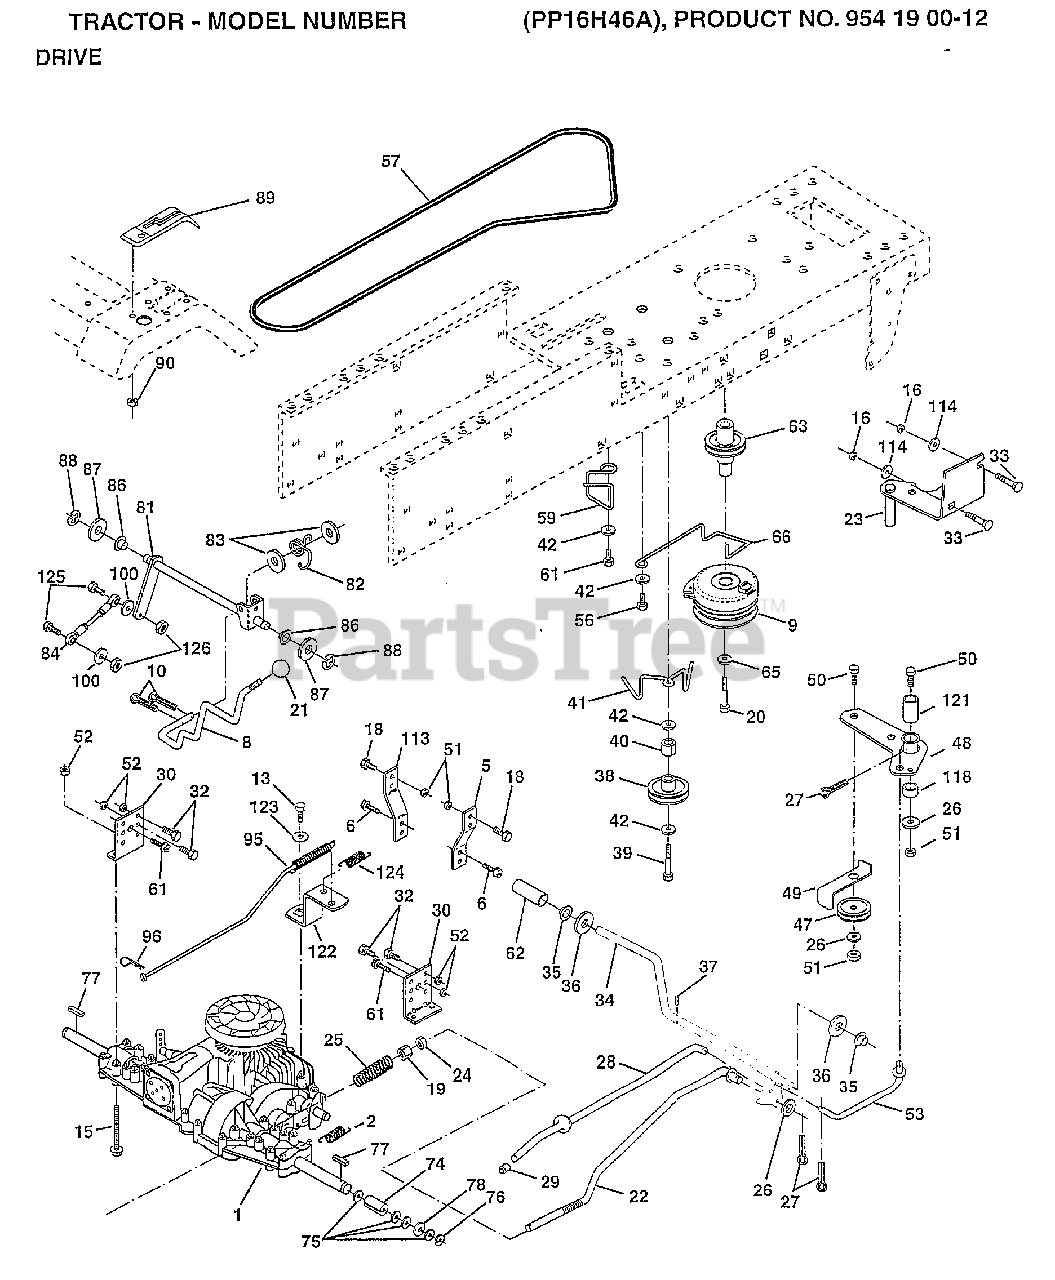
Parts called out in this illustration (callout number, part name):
2	SPRING.BRAKE.RETU
3	PULLEY.TRANSAXLE
5	STRAP TORQUE
6	SCREW
8	"ROD SHIFT,FENDER"
9	CLUTCH.ELECT.EVX.
10	PIN COTTER 1/8
13	BOLT.1/4-28.W/PAT
15	BOLT.HX.FLG.5/16
16	NUT
18	BOLT
19	NUT
20	BOLT.7/16-20X4.25
21	KNOB.DUCKHEAD.1/2
22	BRAKE ROD
23	BRACKET.CLUT.MTG.
24	NUT
25	SPRING ROD LT
26	WASHER
27	COTTER PIN
28	ROD.BRAKE.PARK.LT
29	PLUNGER CAP T
30	TRANSAXLE MTG BKT
32	BOLT
33	BOLT
34	SHAFT ASM-PEDAL F
35	NYLON BEARING
36	WASHER LT
38	PULLEY.IDLER.FLAT
39	BOLT
40	SPACER T
42	WASHER
48	BELLCRANK ASM
49	RETAIN BELT
53	"LINK, CLUTCH T"
55	"SPRING, RETURN LT"
57	"V-BELT,GRD DRIVE"
59	KEEPER BELT CNTSP
61	SCREW
62	PEDAL COVER T
63	PULLEY.CLUTCH.EVX
65	LOCKWASHER
66	KEEPER-BELT
74	"SPACER AXLE,PVST"
75	WASHER
76	E-RING LT
77	SQUARE KEY
78	WASHER
81	SHAFT ASM CROSS
82	"SPRING,TORSION"
83	WASHER
84	"ROD TIE, PVST 20"""
86	BUSHING
87	WASHER D
88	KLIP RING
90	NUT
95	ROAD ASM BYPASS
96	RETAINER M
100	WASHER M
113	"STRAP,TORQUE"
114	WASHER
118	SPACER-BELLCRANK
121	NYLINER-CLUTCHING
122	"PLATE-BYPASS,PVST"
123	WASHER
